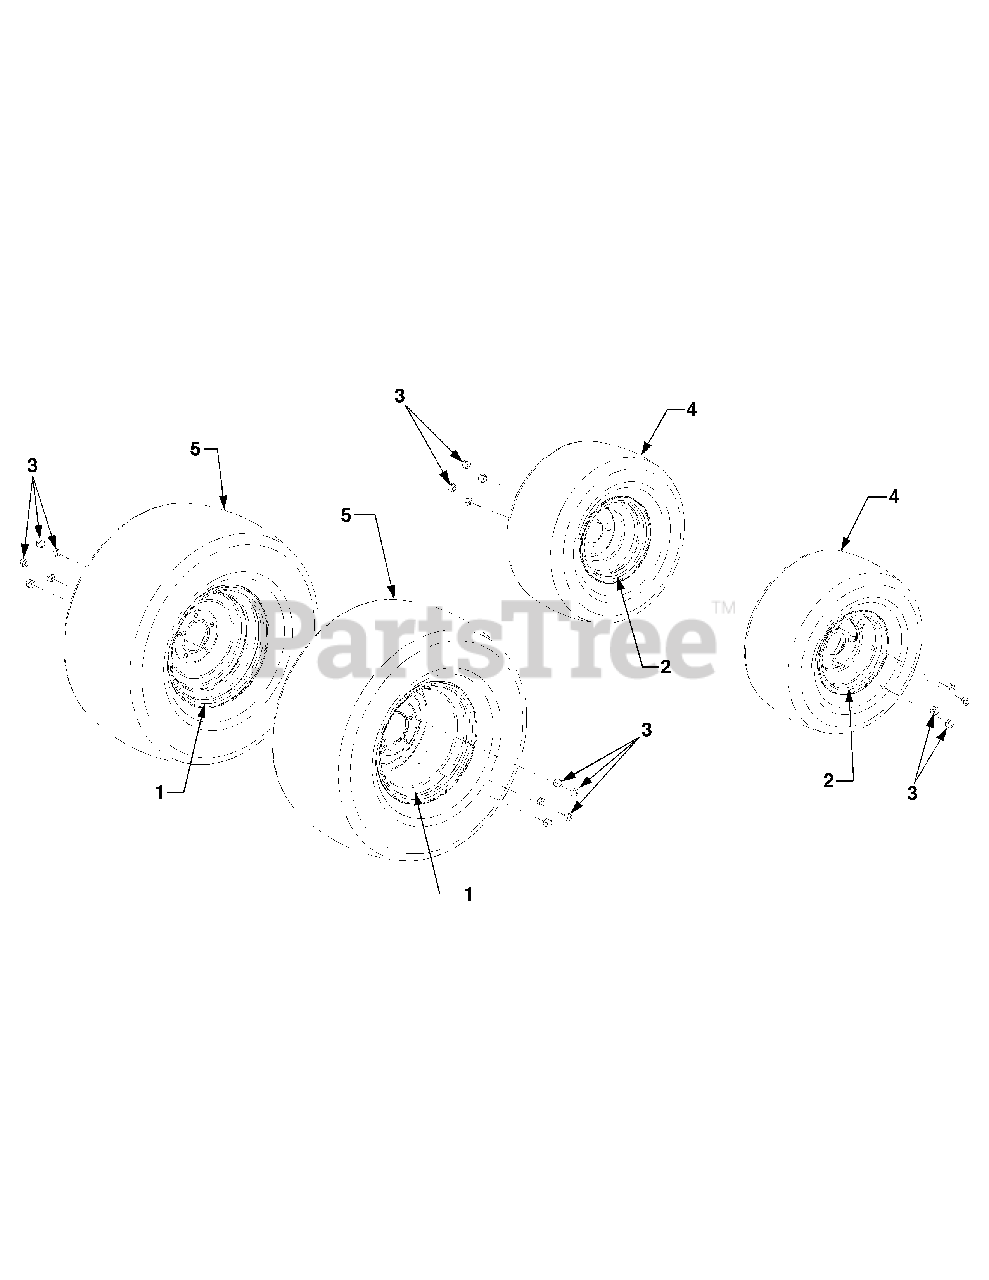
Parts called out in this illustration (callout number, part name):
1	Rim Assembly
1	Valve Stem
2	Rim Assembly, Turf Tire
2	Rim Assembly, Ag Tire
2	Valve Stem
3	Nut, Lug, 7/16-14
4	Tire, Turf, 18 x 8.5 x 8
4	Tire, Ag, 18 x 9.5 x 8
5	Tire, Turf, 26 x 12.0 x 12
5	Tire, Ag, 26 x 12 x 12
